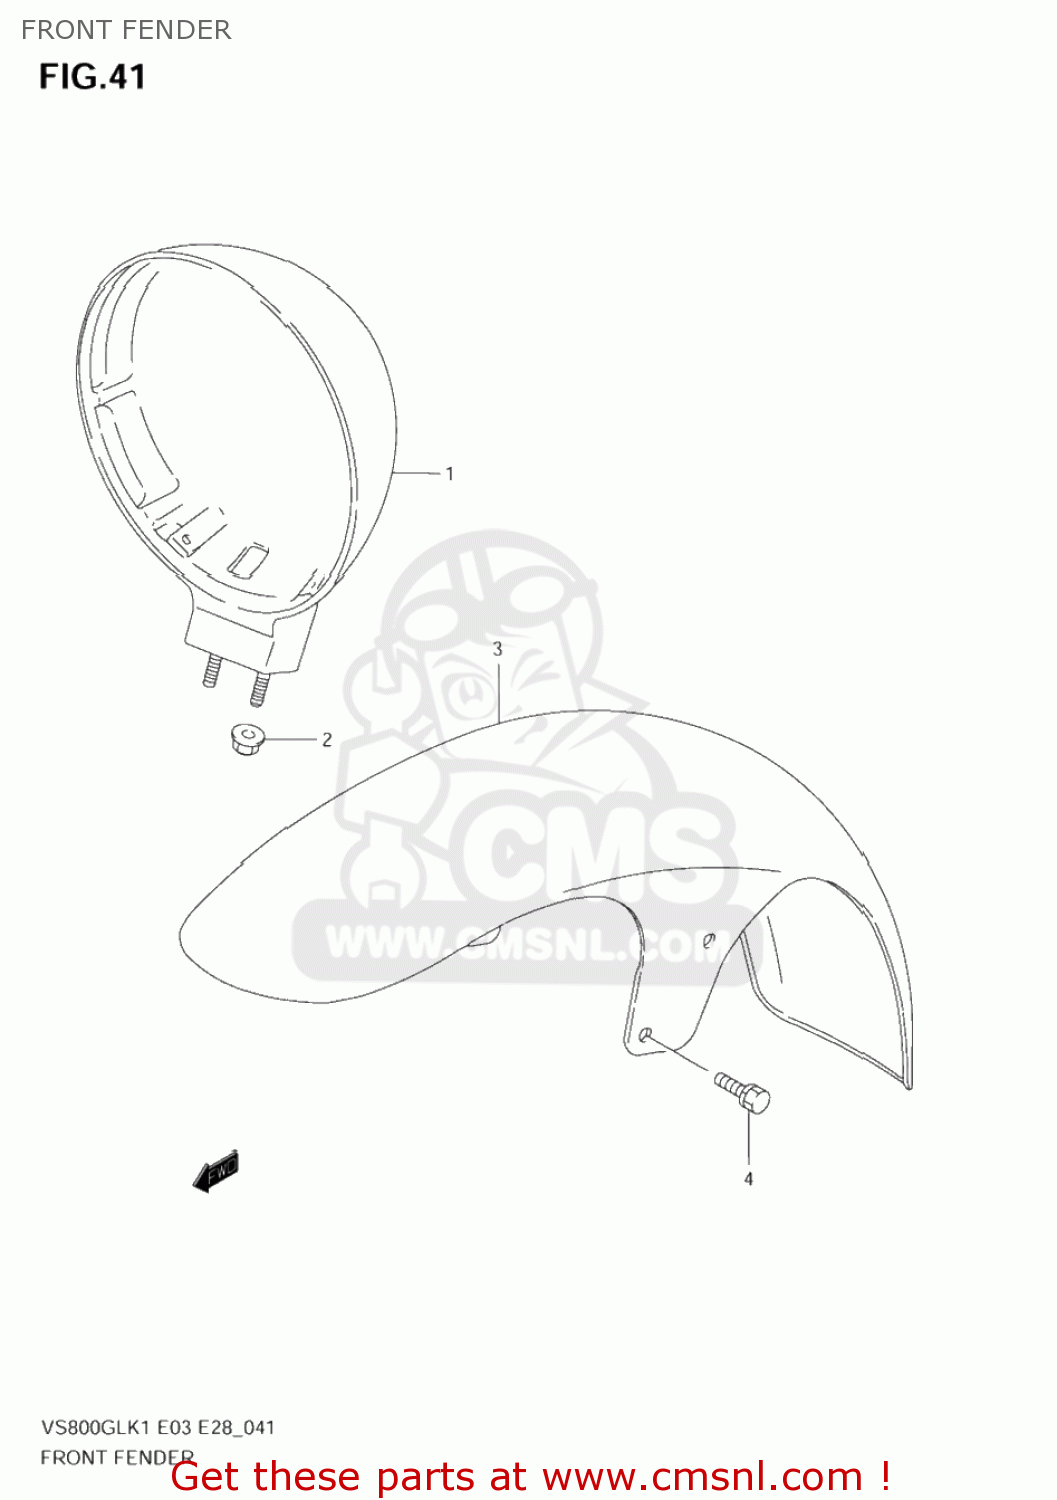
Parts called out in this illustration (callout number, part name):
1	HOUSING,HEADLAMP
2	NUT
3	FENDER,FR
4	BOLT
